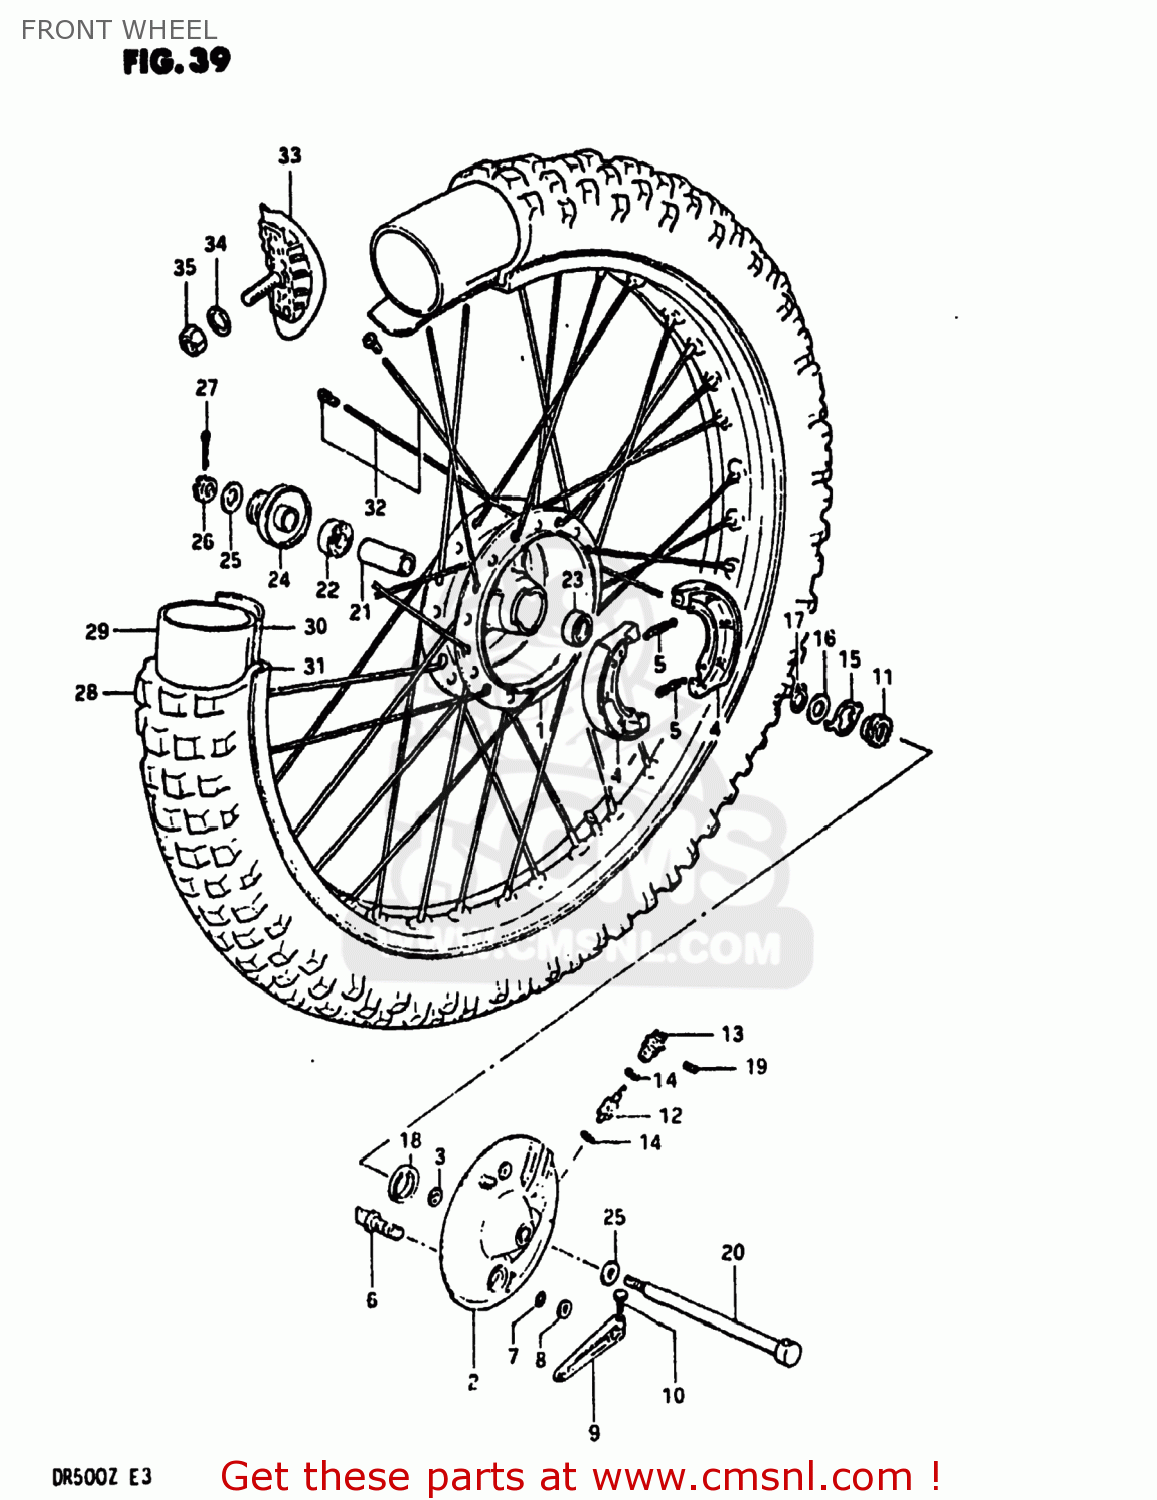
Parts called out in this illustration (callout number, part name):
1	HUB,FRONT
2	PANEL,FRONT HUB
3	BOSS
4	SHOE,BRAKE (MCA)
5	SPRING(L:34)
6	CAM,FRONT BRAKE
7	O-RING (D:2.4 ID:13.8)
8	WASHER (14.5X22X1.6)
9	LEVER,FRONT BRAKE CAM
10	BOLT
11	GEAR,SPEEDOMETER
12	PINION,SPEEDOMETER
13	BUSH,METER GEAR OUTER
14	WASHER (5.1X9X0.4)
15	DRIVER,SPEEDOMETER GEAR
16	WASHER(18.5X24X1)
17	CIRCLIP
18	OIL SEAL (43X58X7)
19	SCREW
20	AXLE,FRONT
21	SPACER (12.6X19X52)
22	BEARING, RH
23	BEARING
24	SPACER,FRONT AXLE,RIGHT
25	WASHER
26	NUT, REAR AXLE
27	COTTER PIN
28	TIRE,FRONT
29	TUBE,INNER
30	PROTECTOR,WHEEL,INNER
31	RIM,FRONT WHEEL
32	SPOKE SET,FRONT
33	STOPPER,BEAD
34	WASHER
35	NUT
